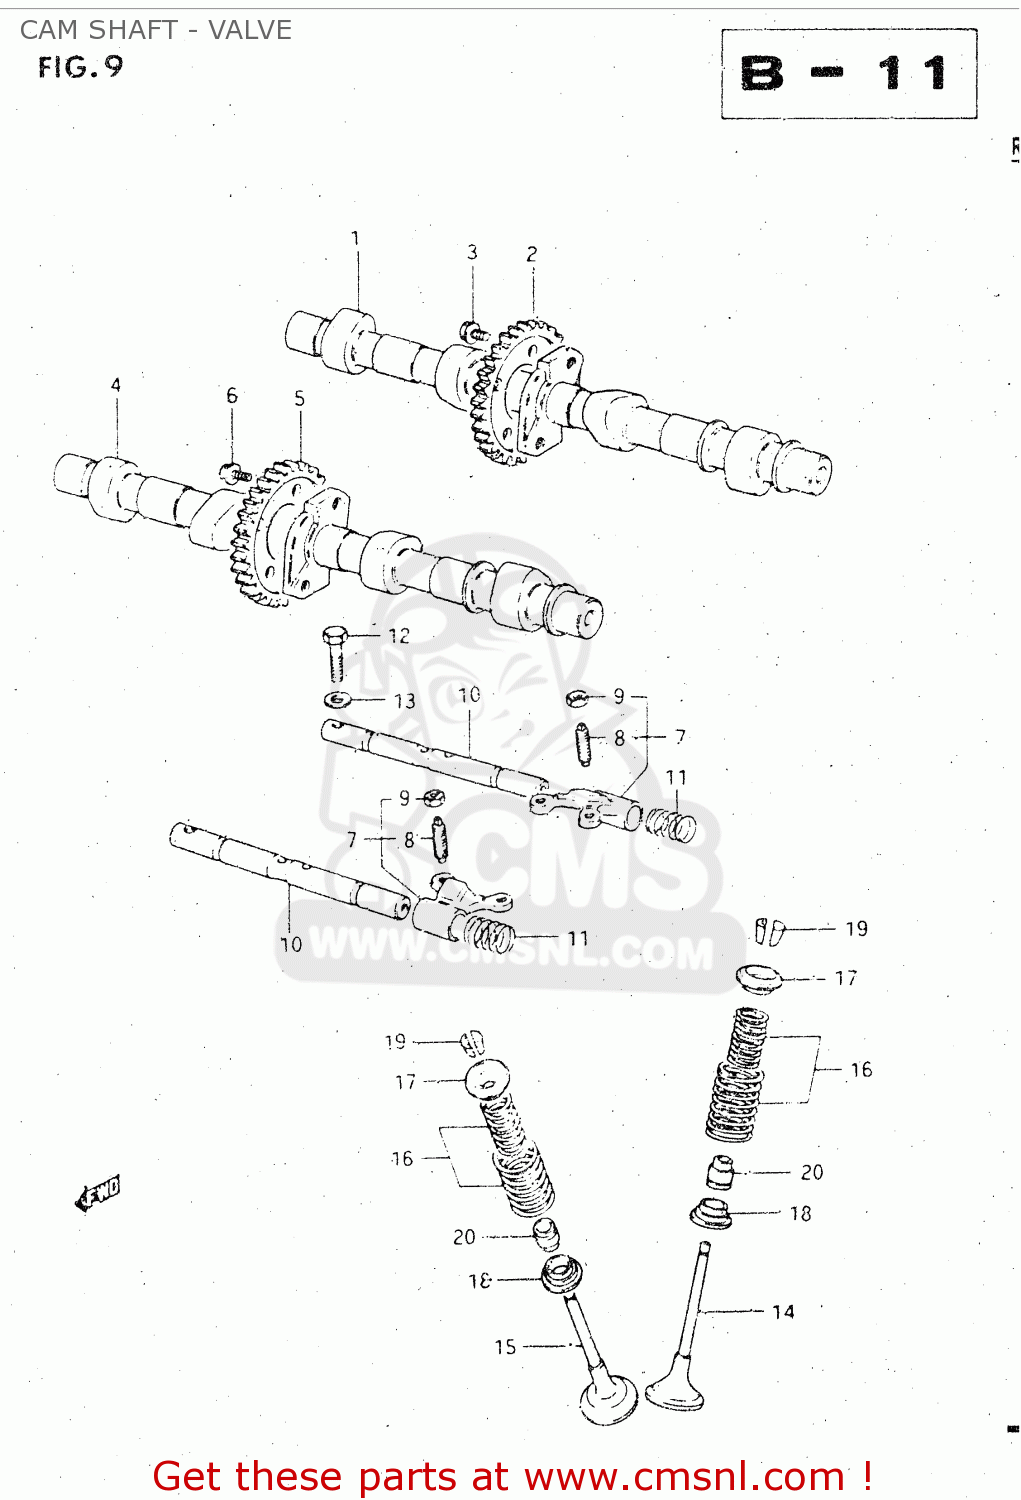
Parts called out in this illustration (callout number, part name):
1	CAMSHAFT,INTAKE
2	SPROCKET,INTAKE CAMSHAFT
3	BOLT(7X11)
4	CAMSHAFT,EXHAUST
5	SPROCKET,INTAKE CAMSHAFT
6	BOLT(7X11)
7	ARM,VALVE ROCKER
8	SCREW,TAPPET ADJUSTING
9	NUT,ADJUSTING
10	SHAFT,VALVE ROCKER
11	SPRING
12	BOLT
13	WASHER, LOWER
14	VALVE,INTAKE
15	VALVE,EXHAUST
16	SPRING SET,VALVE
17	RETAINER,VALVE SPRING
18	SEAT,VALVE SPRING
19	COTTER,VALVE
20	SEAL,OIL(5X10.5X8.4)
